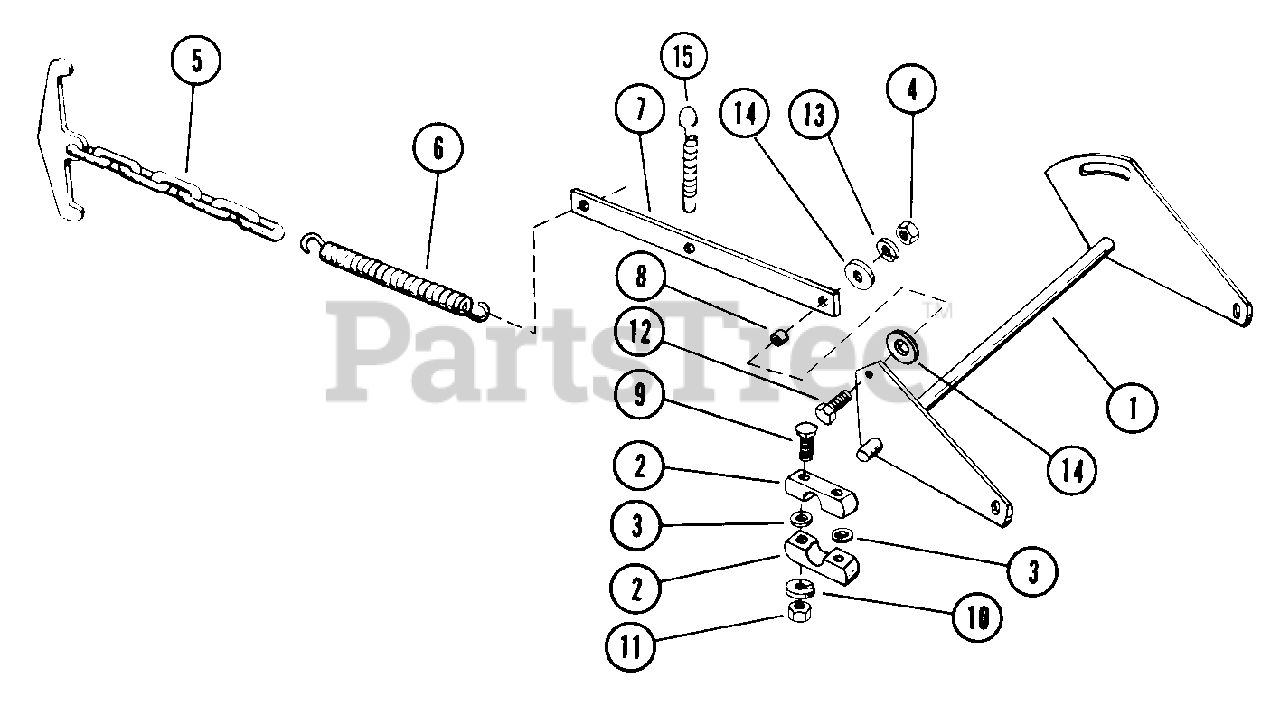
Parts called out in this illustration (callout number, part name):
1	CENTER ROCKSHAFT
3	WSHR-FL-STL .406X.750X.005
4	NUT-HEX .250-20 PL
6	SG-TENS .156X1.062X8.68 WLD ??
8	SPACER .269X.375X.343
9	BLT-RDHDSQNK .38-16X2.25 SHTPL
10	WSHR-LK .375X.094 MED PL
11	NUT-HEX .375-16
12	BLT-HEX .25-20X1.00 GR2
13	WSHR-LK .250X.077 HVY PL
14	WSHR-FL-STL.281X.62X.065 PL
15	SG-TENS .035X.45X2.75 WLD 3.5
